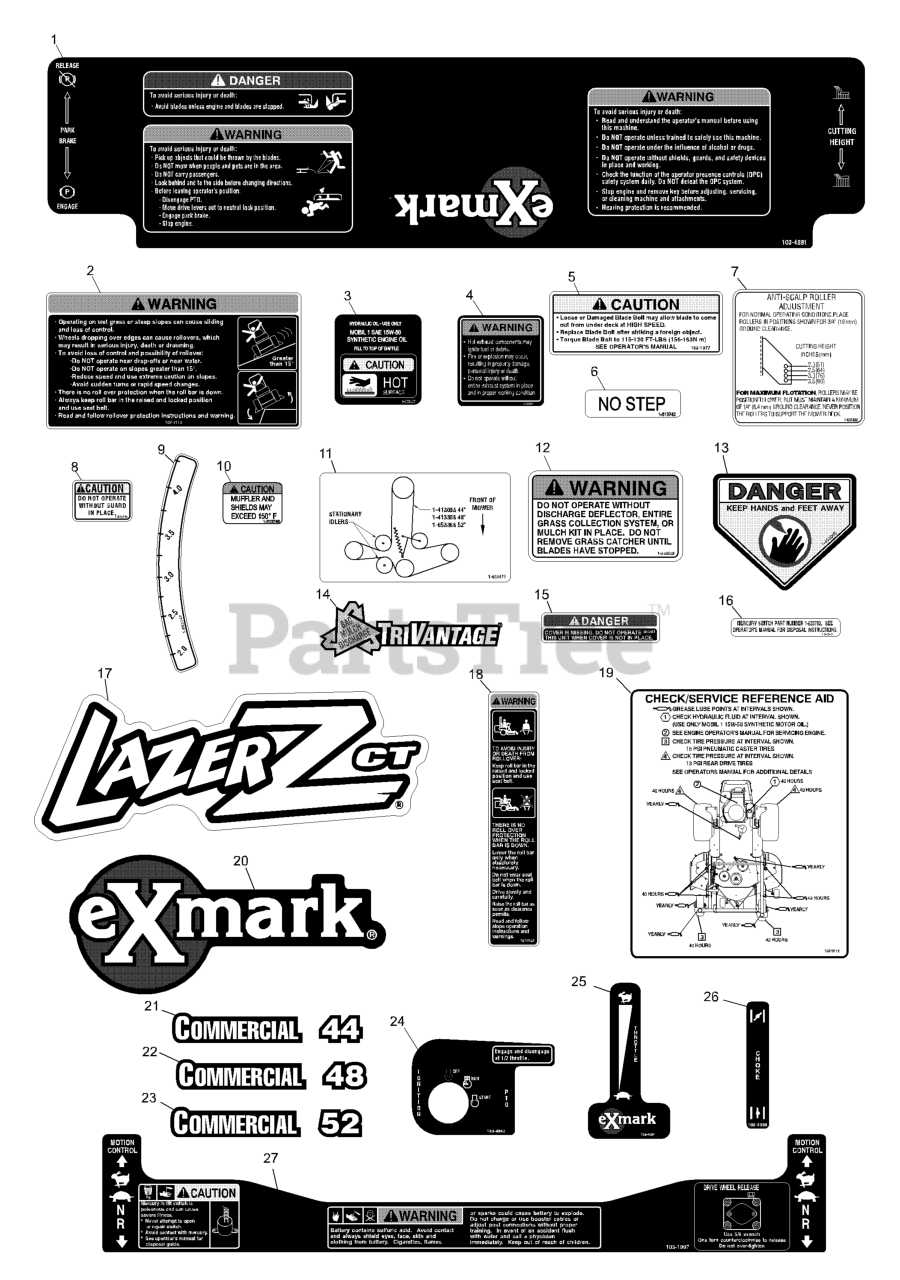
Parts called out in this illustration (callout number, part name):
1	DECAL,CONSOLE LHP
2	DECAL-WARNING
4	DECAL-EXHAUST
5	DECAL,BOLT TORQUE
6	DECAL,NO STEP
7	DECAL,ANTISCALP
8	DECAL-GUARD
9	DECAL-DECK HEIGHT, INNER
12	DECAL-WARNING, DISCHARGE
13	DECAL-DANGER
15	DECAL-COVER, MISSING
16	DECAL-SWITCH, MERCURY
17	DECAL,LCT MODEL
18	DECAL-WARNING, FOLDING RO
19	DECAL, CHECK/SERVICE LCT
20	DECAL,EXMARK LOGO
21	DECAL,COMMERCIAL 44
22	DECAL,COMMERCIAL 48
23	DECAL,COMMERCIAL 52
24	DECAL,IGNITION/PTO
25	DECAL,THROTTLE
26	DECAL,CHOKE
